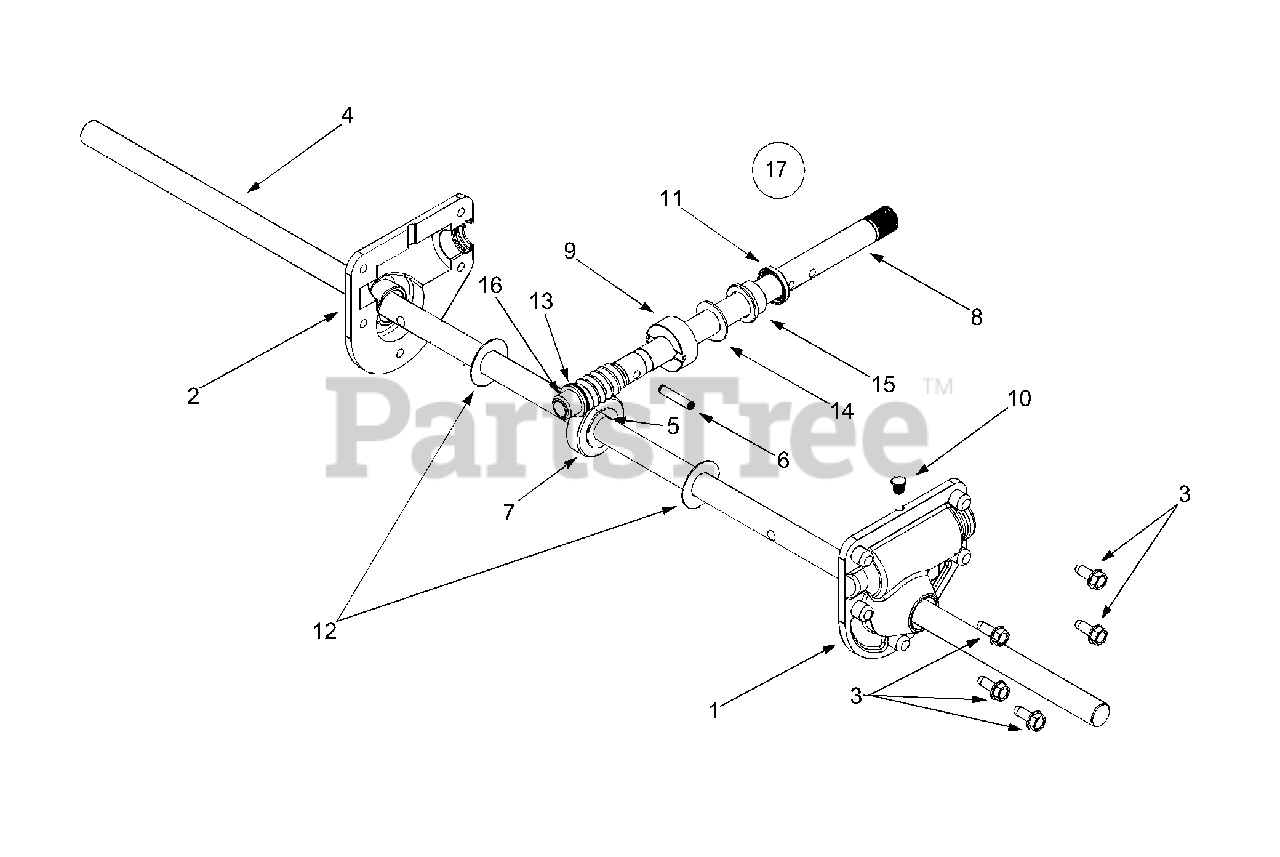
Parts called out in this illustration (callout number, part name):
1	RH Reducer Housing
2	LH Reducer Housing
3	Hex Screw 1/4-20 x .75
4	Spiral Axle 24"
4	Spiral Axle 28"
6	Pin-Spiral
7	Worm Gear, 20T
8	Worm Shaft
9	Thrust Collar
10	Grease Plug
11	Grease Seal
12	Flat Washer .76 x 1.5 x .030
13	Flat Washer .508 x 1.0 x .020
14	Flat Washer .76 x 1.5 x .060
15	Flange Bearing .75 x 1.0 x .59
16	Flange Bearing .75 x 1.0 x .925
17	Ass'y. Complete 24"
17	Ass'y. Complete 28"
